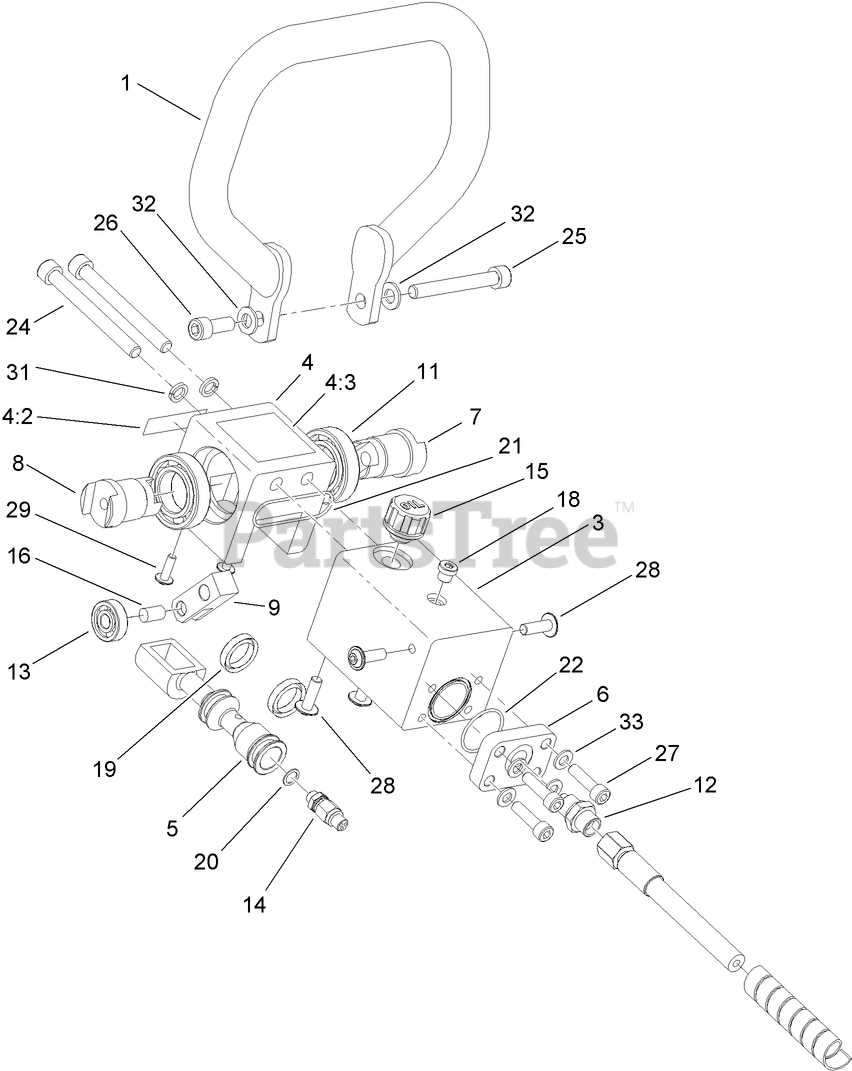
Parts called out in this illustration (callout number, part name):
1	HANDLE-CONTROL, TRAVEL
3	MANIFOLD-VALVE
4	MANIFOLD-VALVE, UPPER
4:2	DECAL-CAUTION
4:3	DECAL-OPERATION
5	SPOOL-VALVE
6	COVER-END
7	PIVOT-LEFT
8	PIVOT-RIGHT
9	ARM-PIVOT
11	BEARING
12	SOCKET
13	BEARING
14	VALVE-CHECK
19	PACKING
20	RING-ALUMINUM
21	O-RING
22	O-RING
31	WASHER
32	WASHER
33	WASHER
